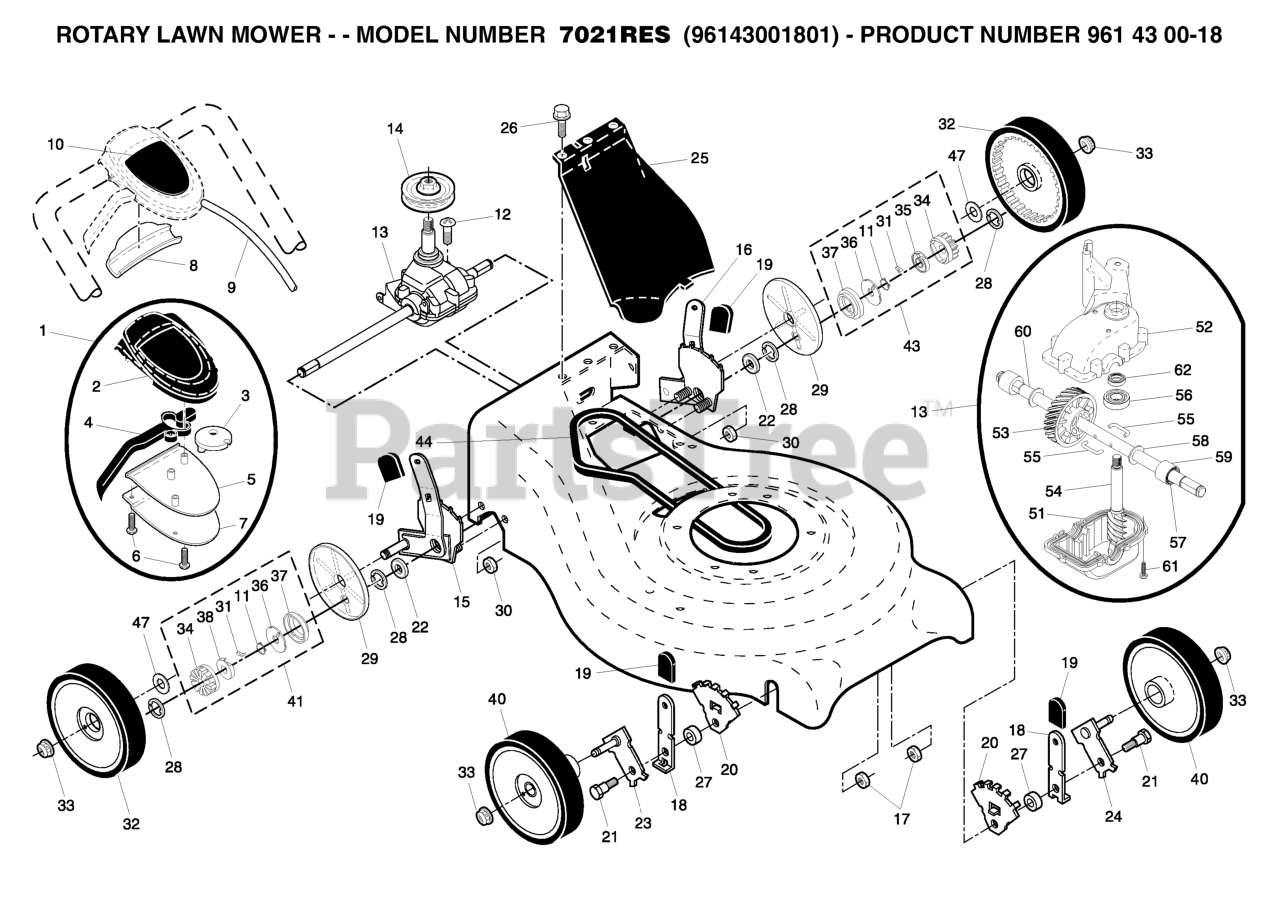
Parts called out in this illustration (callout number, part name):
1	CONTROL.DR.QE.GRY.RGD.BLUE.4PT
2	CASE.TOP.GRAY
3	PULLEY.CAM.DRIVE.CONTROL.HV
4	LEVER, AUTOWALK DRIVE CONTROL
5	CASE BOTTOM
6	SCREW, PHILLIPS HEAD 10 X 5/8
7	BRACKET.DRIVE.CONTROL.MOUNT.BL
8	EZ WALK SNAP COVER PLATE
9	CABLE.ASM.EZ.WALK
10	DECAL.DRIVE.CONTROL.HV
11	SPRING, TORSION
13	TRANSMISSION.21.FWGD
14	PULLEY.1.PIECE
15	KIT.ADJUSTER.ASM.EZ(193677).RT
16	KIT.ADJUSER.ASM.EZ
17	LOCKNUT 5/16-18
18	REPL BY 532 1683-60
19	KNOB.DELUXE.GRAY
20	WHEEL BRACKET ADJUSTER
21	SHOULDER BOLT
22	BEARING
23	AXLE ARM ASSY LF
24	AXLE ARM ASSY
25	COVER.DRIVE.21.RWGD.MO
27	SPACER.34X1.38X.22
28	E-RING 7/16 RE
29	COVER.DUST.WHEEL
30	LOCKNUT.NYLOC.1/4-20
31	PAWL.DRIVE.21.EZ-WALK
32	WHEEL.8X1.75.5SPK.RAD.GREY
33	HEX FLANGE LOCKNT
34	GEAR, PINION
35	RETAINER.DRIVE.21.EZ-WALK.LT
36	DISC.DRIVE.21.EZ-WALK
37	SEAL.PINION
38	RETAINER, DRIVE, RH
40	WHEEL.8X1.75.GREY.RAD3.5SPOKE
41	PINION ASSY, RH
43	PINION ASSY, LH
44	BELT.DRIVE.EZ.WALK.HI-VAC
47	WASHER FLUT
51	CASE, LOWER
52	CASE, UPPER
53	GEAR.24.TOOTH.WALK.MOWER
54	SHAFT INPUT
55	WIRE, FORMED (15966)
57	SEAL.OUTPUT.SHAFT
60	RB OUTPUT.SHAFT.12246
62	SEAL INPUT SHAFT
